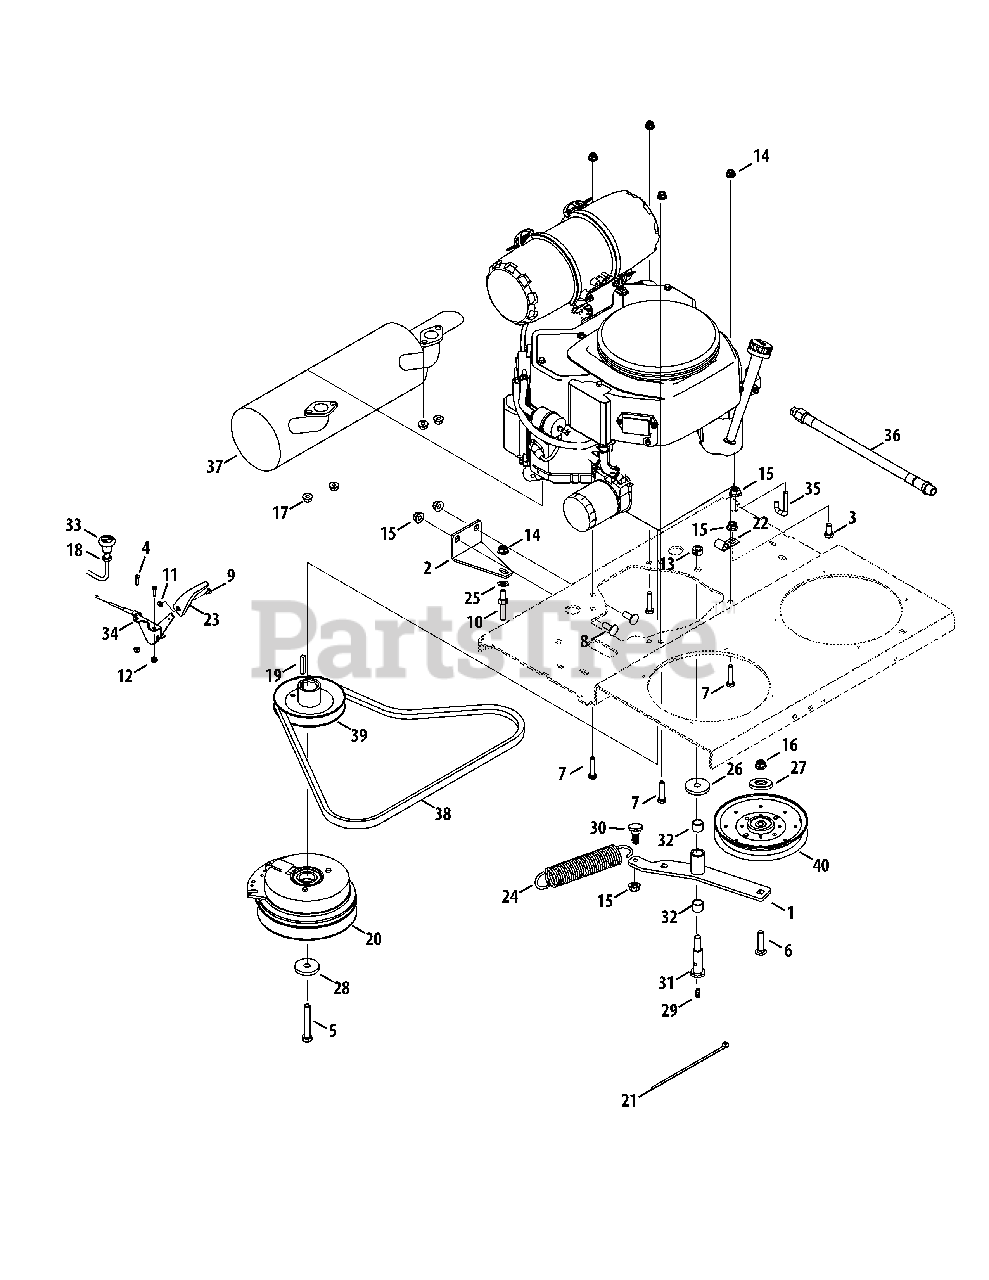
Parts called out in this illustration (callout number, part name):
1	Idler Bracket
2	Clutch Retainer Bracket
3	Hex Cap Screw, 3/8-16 x .75
4	Screw, #10-24 x .625
5	Hex Cap Screw, 7/16-20 x 2.75
6	Carriage Bolt, 3/8-16 x 1.00
7	Hex Cap Screw, 5/16-18 x 1.50
8	Carriage Bolt, 3/8-16 x 1.00
9	Screw, #8-32 x .375
10	Stud, Pivot Ball Joint
11	Nut, #8-32, Hex
12	Nut, #10-24, Hexlock
13	Nut, 7/16-14, Hexlock
14	Nut, 5/16-18, Flangelock
15	Nut, 3/8-16, Flangelock
16	Nut, 3/8-16, Flangelock
17	Nut, M8-1.25, Hexlock
18	Jam Nut, 3/8-24
19	Key, 1/4 x 1.50
20	Electric PTO Clutch
21	Cable Tie
22	Clip, .407 x 1.80
23	Throttle Control Knob
24	Extension Spring, 1.5 x 7.5
25	Washer, .344 x .688 x .065
26	Washer, .471 x 1.50 x .225
27	Pulley Cap
28	Washer, .471 x 1.50 x .225
29	Grease Fitting
30	Shoulder Screw, .625 x .302, 3/8-16
31	Shoulder Bolt, .625 x 1.947, 7/16-14
32	bearing, .638 x .753 x .615
33	Choke Control Cable
34	Throttle Cable
35	Transmission Spring Hook
36	Oil Drain Hose
37	Muffler
39	Drive Pulley
40	Idler Pulley
